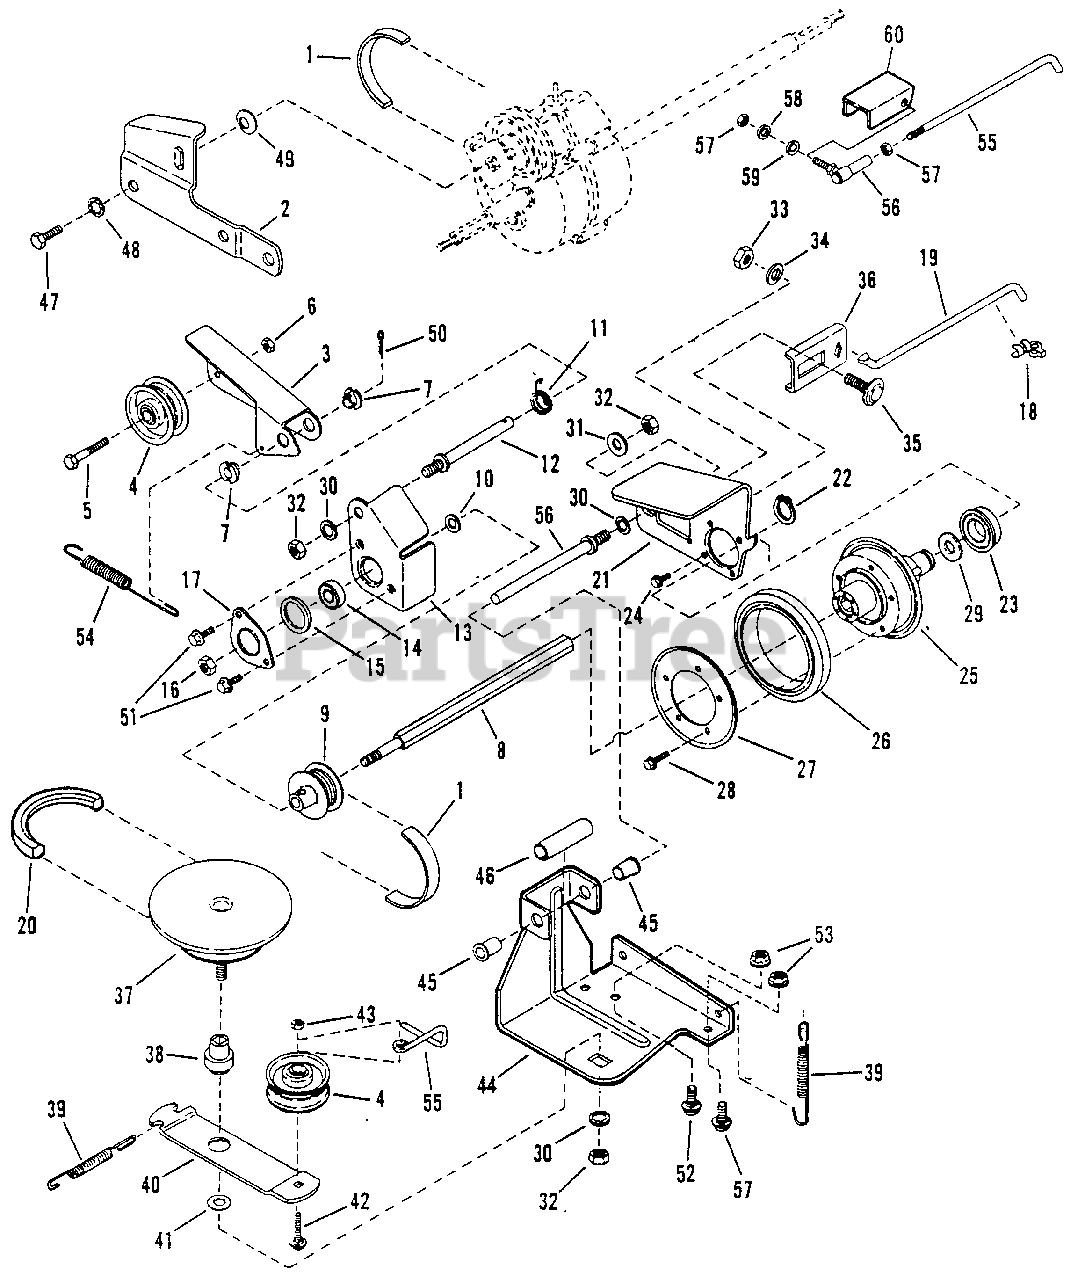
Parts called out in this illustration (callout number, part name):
1	BELT, Poly-Vee
2	LINK, Differential
3	ARM, Clutch Idler
4	PULLEY, Idler
5	SCREW, 1/4-28 x 1-3/8" Hex Head Cap, Grade 5
6	NUT, 1/4-28 Hex Top Lock
7	BUSHING, 3/8 l.D. Nylon
8	SHAFT, Hex Drive
9	PULLEY, Poly-V (2" O.D )
10	WASHER, 3/8" Flat
11	SPRING, Torsion
12	STUD
13	HOLDER, Bearing (Inner Half)
14	BEARING, Ball
15	O-RING
16	NUT, 3/8-24 Hex Center Lock, Grade 5
17	HOLDER, Bearing (Outer Half)
18	CLIP, 1/4 Right Arc (Transfer Rod)
19	ROD, Transfer
20	BELT, Engine Drive
21	PLATE, Thrust
22	RING, Retaining
23	BEARING, Ball
24	SCREW, #10-32 x 1/4" Self-Tapping Machine
25	ASSEMBLY, Hub (Includes 11108 Bushing & 90913 Screws)
26	RING, Driven
27	PLATE, Ring Retaining
28	SCREW, #10-24 x 1/2" Hex Washer Self-Tap (Torx)
29	WASHER, 3/4 Shim
30	WASHER, 3/8 Internal Tooth Lock
31	WASHER, 3/8" Flat
32	NUT, 3/8-24 Hex, Grade B
33	NUT, 5/16-18 Hex, Grade 5
34	WASHER, 5/16 Split Lock
35	BOLT, 5/16-18 x 3/4" Carriage, Grade 5
36	CONNECTOR, Transfer Rod
37	KIT, Drive Disc Assembly
38	BUSHING
39	SPRING (Wheel Drive & Idler)
40	ARM, Idler
41	RETAINER, 3/8 Bolt
42	BOLT, 1/4-20 x 1-1/2" Carriage, Grade 5
43	NUT, 1/4-20 Hex Center Lock, Grade 5
44	BRACKET, Deck
45	BUSHING, Flange
46	SPACER
47	SCREW, 5/16-18 x 1/2" Hex Head Cap, Grade 5
48	WASHER, 5/16 internal Tooth Lock
49	WASHER, Spring
50	PIN, 3/32 x 1/2" Cotter
51	SCREW, 1/4-20 x 1/2" Self-Tapping
52	BOLT, 5/16-18 x 1/2" Short Neck Carriage, Grade 5
53	NUT, 5/16-18 Hex Flange Lock, Grade 5
54	SPRING, Clutch
55	SCRAPER, Drive Pulley
56	GUIDE, Thrust Plate
57	BOLT, 5/16-18 X 5/8" Short Neck Carriage, Grade 5
58	WASHER, 1/4 Internal Tooth Lock
59	WASHER, 1/4 Flat
60	SHIELD, Hex Shaft
